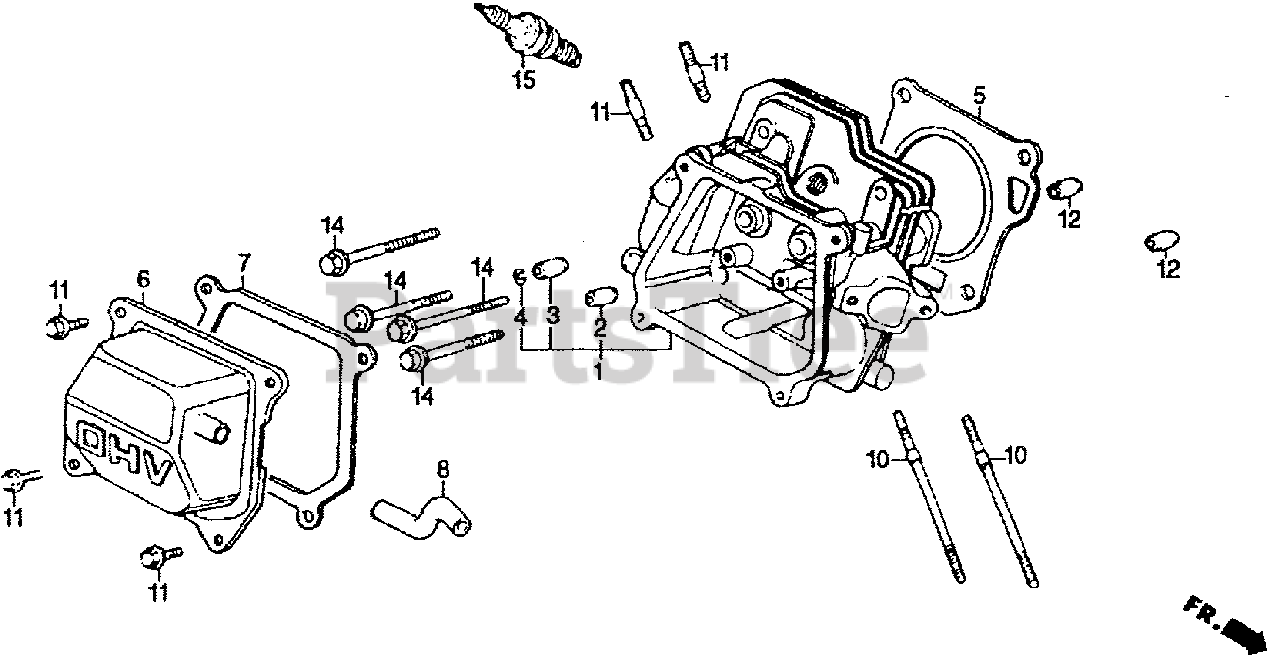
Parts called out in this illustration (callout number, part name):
1	CYLINDER HEAD
2	GUIDE, VALVE (OS)
3	GUIDE, EX. VALVE (OS)
4	CLIP, VALVE GUIDE
5	GASKET, CYLINDER HEAD
6	COVER, HEAD
7	GASKET, CYLINDER HEAD COVER
8	TUBE, BREATHER
9	BOLT, FLANGE (6X13)
10	BOLT, STUD (6X109)
11	BOLT, STUD (8X32)
12	PIN A, DOWEL (10X16)
14	BOLT, FLANGE (8X60)
15	SPARK PLUG (BPR6ES) (NGK)
15	SPARK PLUG (W20EPR-U) (DENSO)
